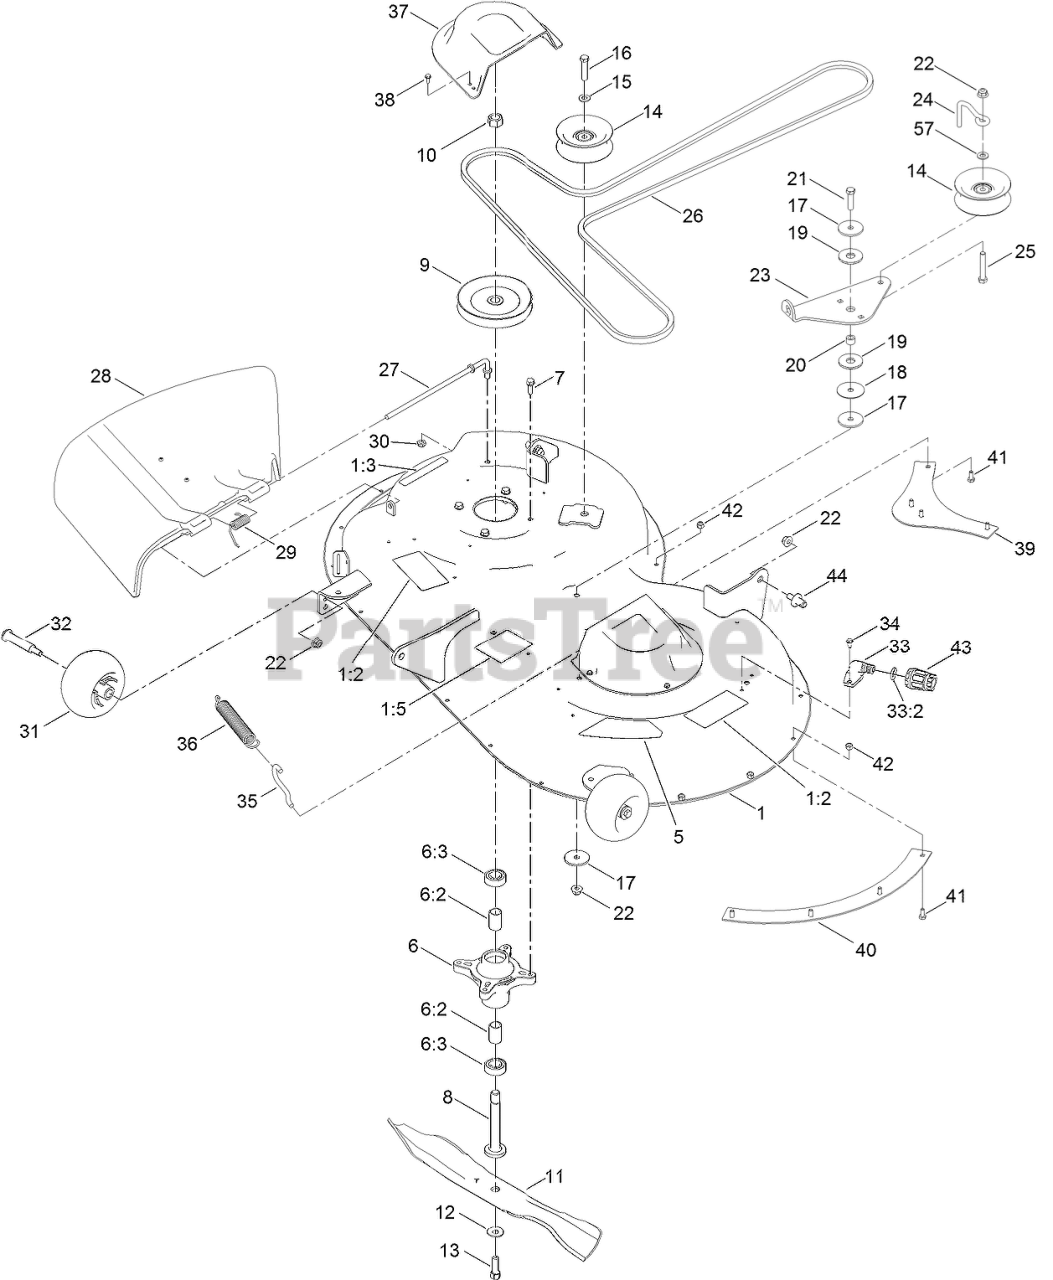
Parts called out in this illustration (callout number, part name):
1	42 INCH DECK AND DECAL ASM
1:2	DECAL-DANGER, DECK
1:3	DECAL-DANGER
1:5	DECAL-ROUTING, BELT
6	SPINDLE ASM
6:2	SPACER
6:3	BEARING-BALL
7	SCREW-TAPTITE
8	SHAFT-SPINDLE
9	Pulley
10	NUT-HEX
11	BLADE-21.6 IN
12	WASHER-BELLEVILLE
13	SCREW-HH
14	PULLEY-IDLER, FLAT
15	WASHER-FLAT
16	SCREW-HH
17	WASHER-REBOUND
18	WASHER
19	WASHER-FRICTION, COMPOSITE
20	SPACER
21	SCREW-HH
22	NUT-HF, NI
23	ARM-IDLER
24	BELT GUIDE - IDLER
25	SCREW-HH
26	V-BELT
27	ROD-PIVOT
28	DEFLECTOR
29	SPRING-TORSION
31	ROLLER-SCALP, ANTI
32	BOLT-SHOULDER
33	FITTING-WASHOUT
33:2	O-RING
34	SCREW-HWH
35	HOOK-RETURN SPRING
36	SPRING-EXTENSION
37	COVER-BELT
38	SCREW-TAPTITE
39	BAFFLE-BLOWOUT, REAR
40	BAFFLE-BLOWOUT, SIDE
41	SCREW-HH
42	NUT-LOCK, NI
43	CONNECTOR-HOSE
44	PIN-DECK
57	SPACER-HUB, BLOWER
